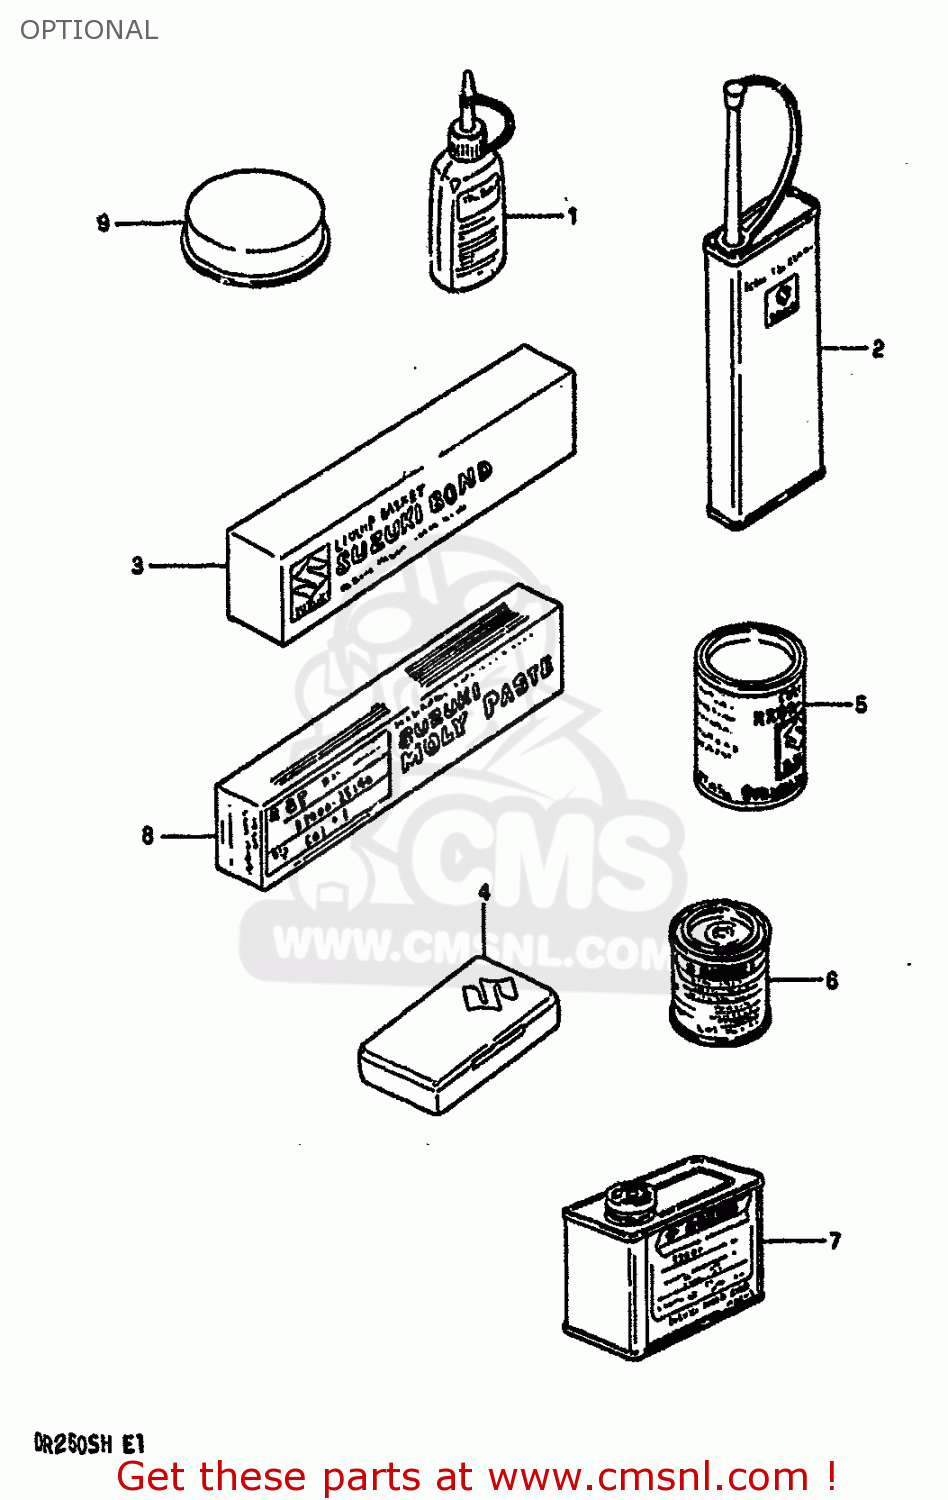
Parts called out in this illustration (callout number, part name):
1	THREAD LOCK NO.1342
2	THREAD LOCK NO.1401 CLEAR 200G
3	LIQUID GSKT NO.1207B 100G BLK
4	TUBE REPARING TOOL
5	GREASE(C)EP2 LITHIUM 150G
6	PAINT,BLACK
7	PAINT (BLACK)
8	SUZUKI MOLY PASTE
9	GREASE,PBC FOR BRK PAD 20G
